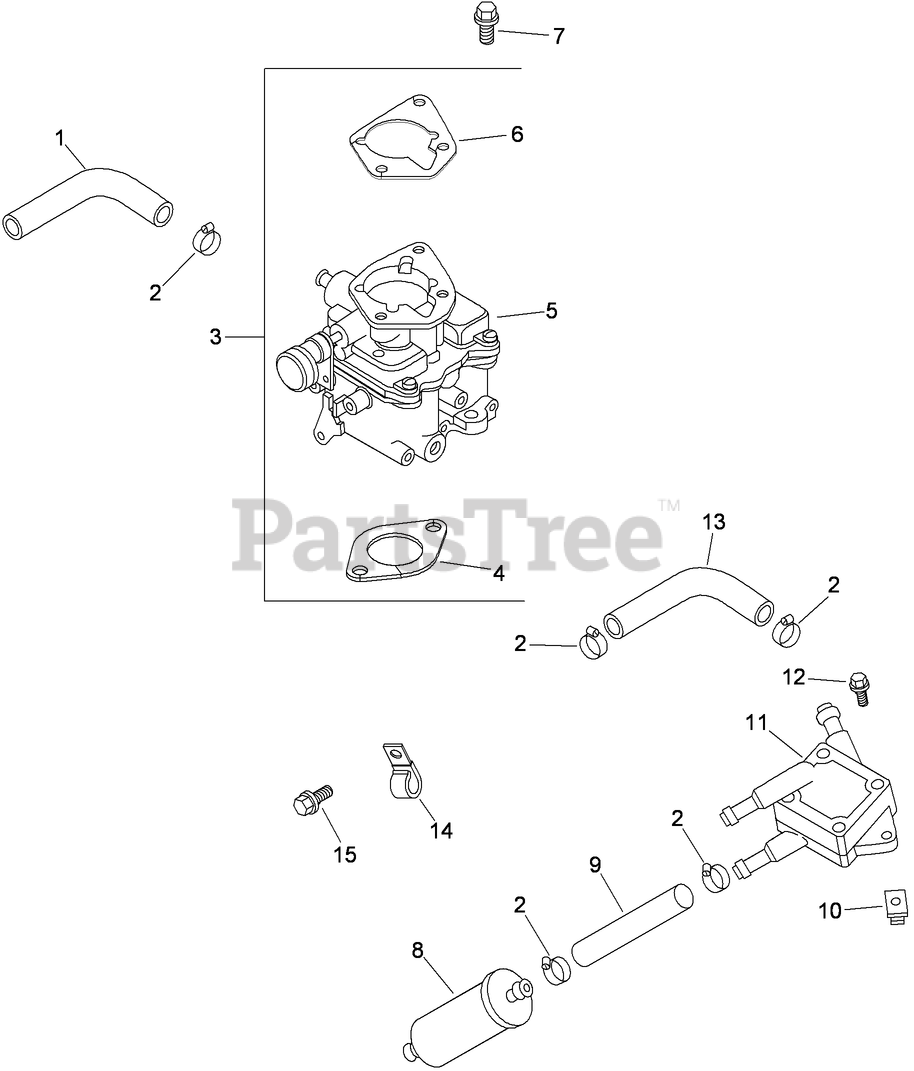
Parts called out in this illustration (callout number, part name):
1	Line-Fuel (9.5)
2	CLAMP-HOSE, SPRING (1/2)
3	Carburetor kit (Includes Ref 4-6)
4	Gasket-Carburetor
5	Carburetor ASM
6	GASKET-BASE, AIR CLEANER
7	SCREW-FLANGE (M6X1.0X30)
8	Filter-Fuel
9	Line-Fuel (3.5)
10	Nut-Plastic
11	PUMP-FUEL
12	SCREW-TAP (M6X1.7X18)
13	Line-Fuel, Flexible (15.5)
14	Screw-HF (M6x1.0x12)
15	CLIP-CABLE
